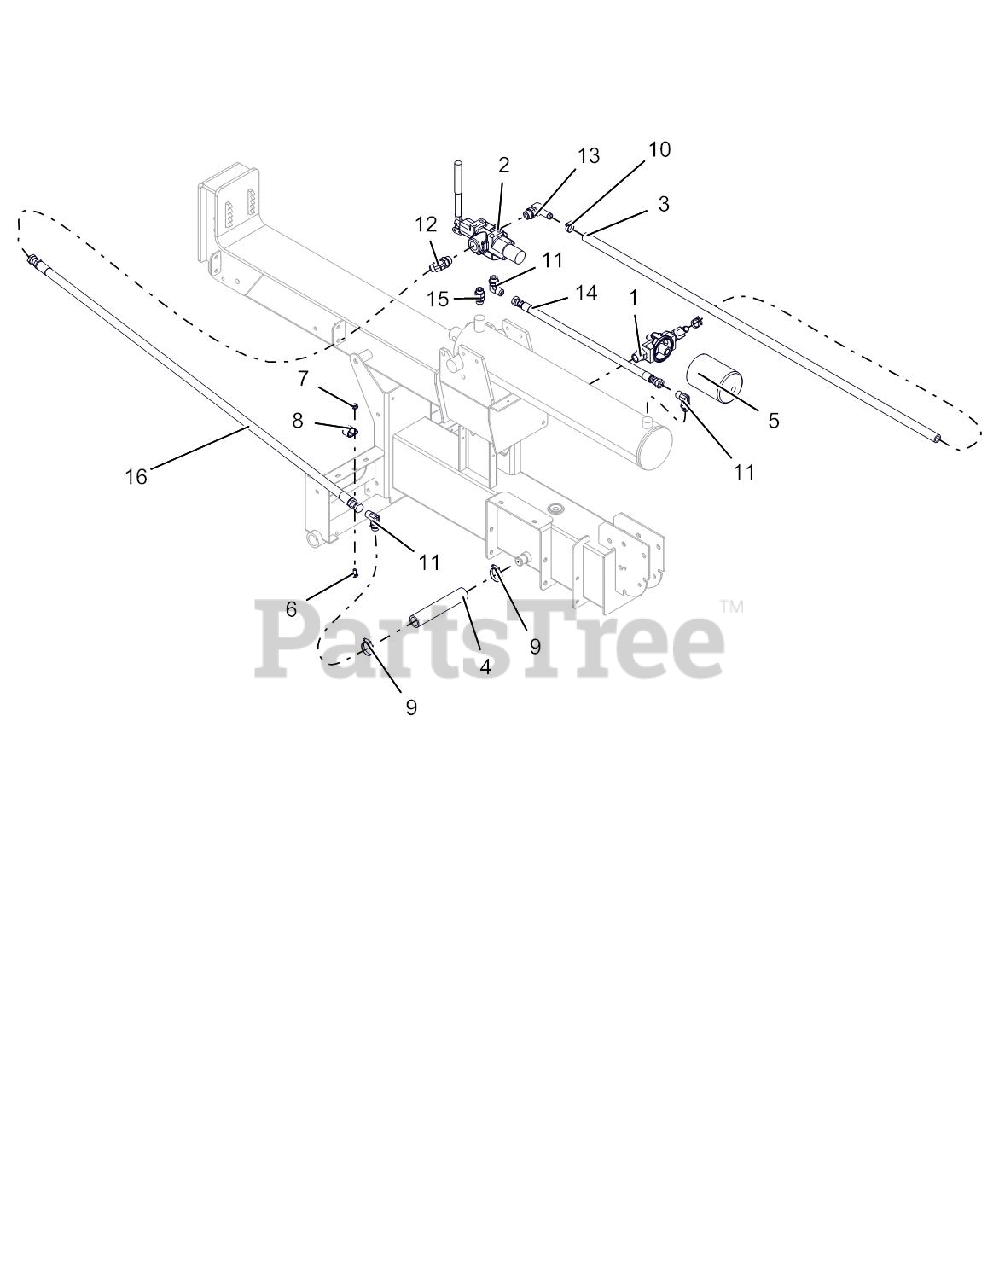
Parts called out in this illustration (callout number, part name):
1	ASM, FILTER HEAD
2	VALVE CONTROL-SPLITTER
3	HOSE,HYD RETURN 10LOLA X 53"
4	HOSE, HYD - SUCTION 7.375"
5	FILTER,HYDRAULIC OIL-NO BYPASS
6	@BLT-RDHDSQNK .31-18X.75 G5YZ
7	@NUT-LK-TOP-FLG .31-18 YWZC
8	CLAMP, COUSHIONED STEEL REV
9	CLAMP-HOSE 1.50X.81X1.42
10	CLAMP,.88 DIA. HOSE
11	FTG,HYD 6801-8-8
12	FTG,HYD 6802-8-10
13	FTG,HYD 4601-10-10
14	HOSE, HYD - 22"
15	FTG, HYD - STR 08MAORB-08MORB
16	HOSE, HYD - 58"
